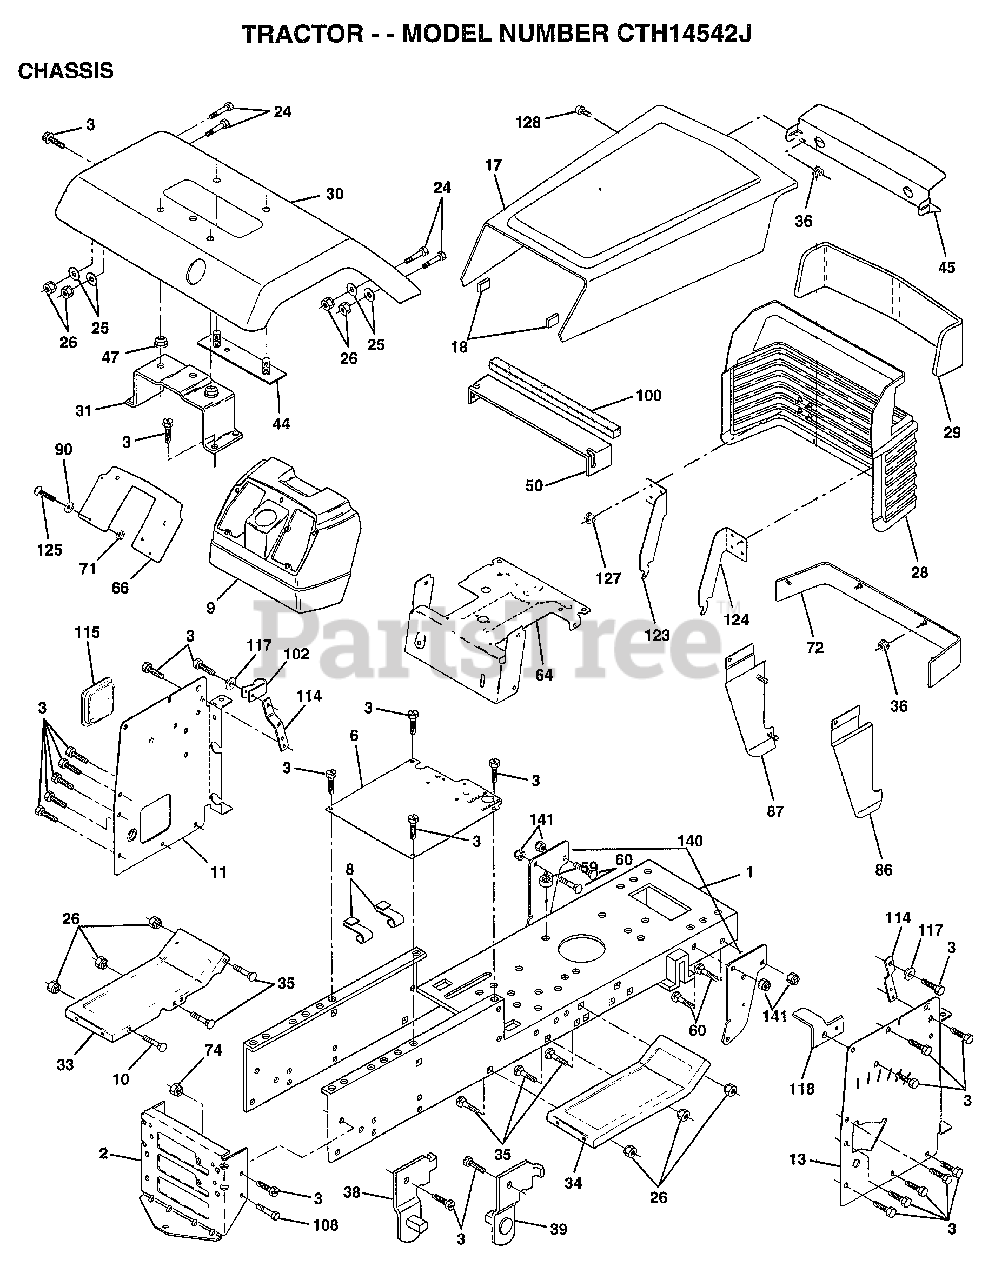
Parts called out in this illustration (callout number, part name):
1	CHASSIS.STAMPING
3	SCREW
6	SADDLE
8	"CLIP,INSULATOR"
9	DASH.PLASTIC.BLK
11	PANEL.DASH.LH.
13	PANEL.DASH.RH.
17	HOOD/GRILLE ASM
24	BOLT
25	WASHER
26	NUT
28	GRILLE ASM WELD
30	FENDER.LTST.WLDMNT.W.SHIFT
31	BRACKET SUPT FEND
33	FOOTREST.LH.LT/GT
34	FOOTREST.RH.LT/GT
35	BOLT
36	PAL NUT LT
37	SCREW LT
38	BRACKET ASM LH
39	BRACKET ASM RH
40	SPACER FENDER LT
45	BEZEL.LIGHT.SLVR
50	"BAFFLE,HOOD"
64	DASH.LOWER.LT
72	STRAP FENDER ASM
86	PANEL SIDE RH ASM
87	PANEL SIDE LH ASM
90	WASHER PM
100	FOAM-STRIP LT
102	CLIP T
114	BRACKET.SUPT.DASH
115	COVER ACCESS
117	WASHER.SERRATED.
118	BRACKET.CLUTCH.MC
123	BRACKET.PICK.LH.
124	BRACKET.PICK.RH.
125	SCREW
127	PAL NUT
128	SCREW SPECIAL
140	BRKT SUSPENSION
145	"ROD POVOT,CHASSIS"
